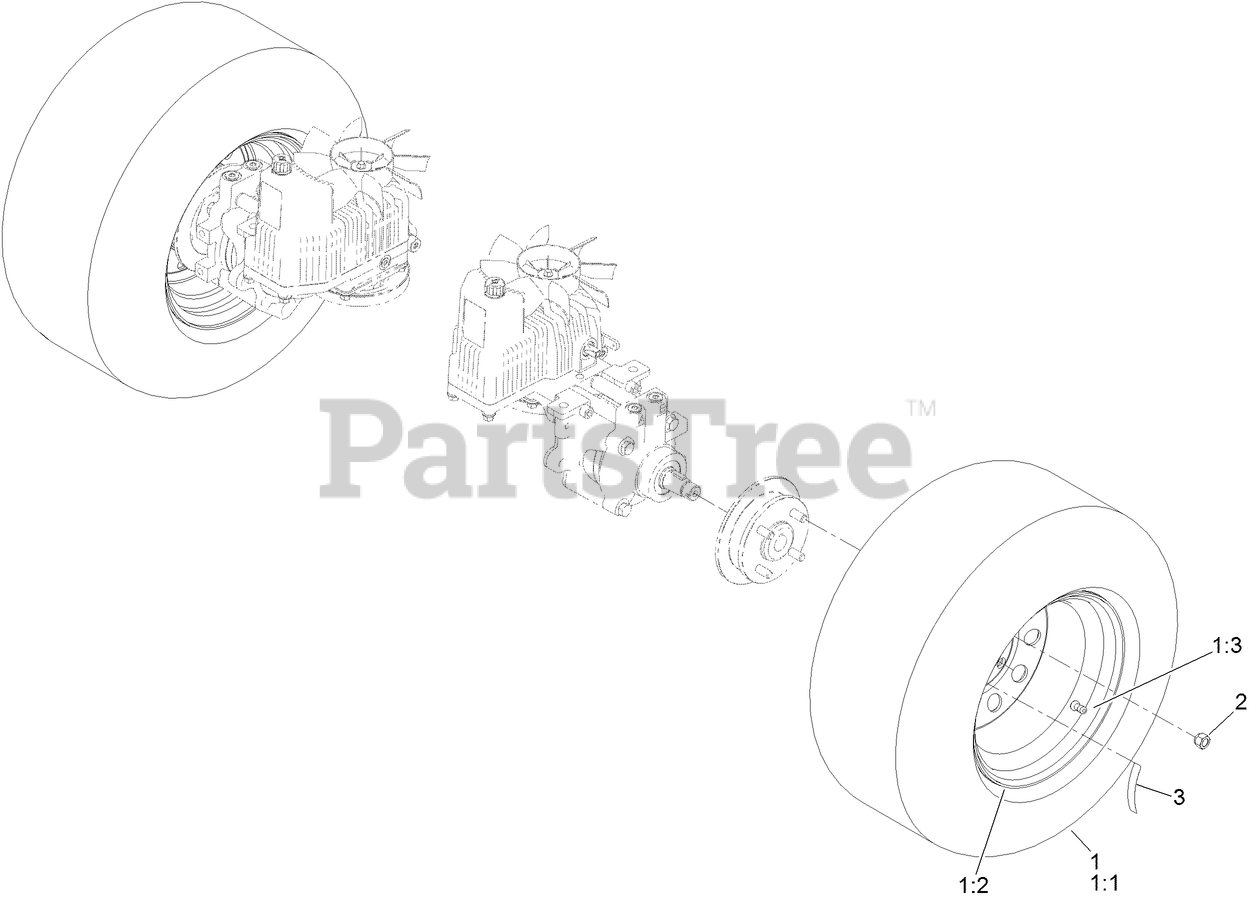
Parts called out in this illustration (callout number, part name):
1	WHEEL AND TIRE ASM
2	NUT-LUG
3	DECAL-TORQUE, WHEEL HUB LUG
